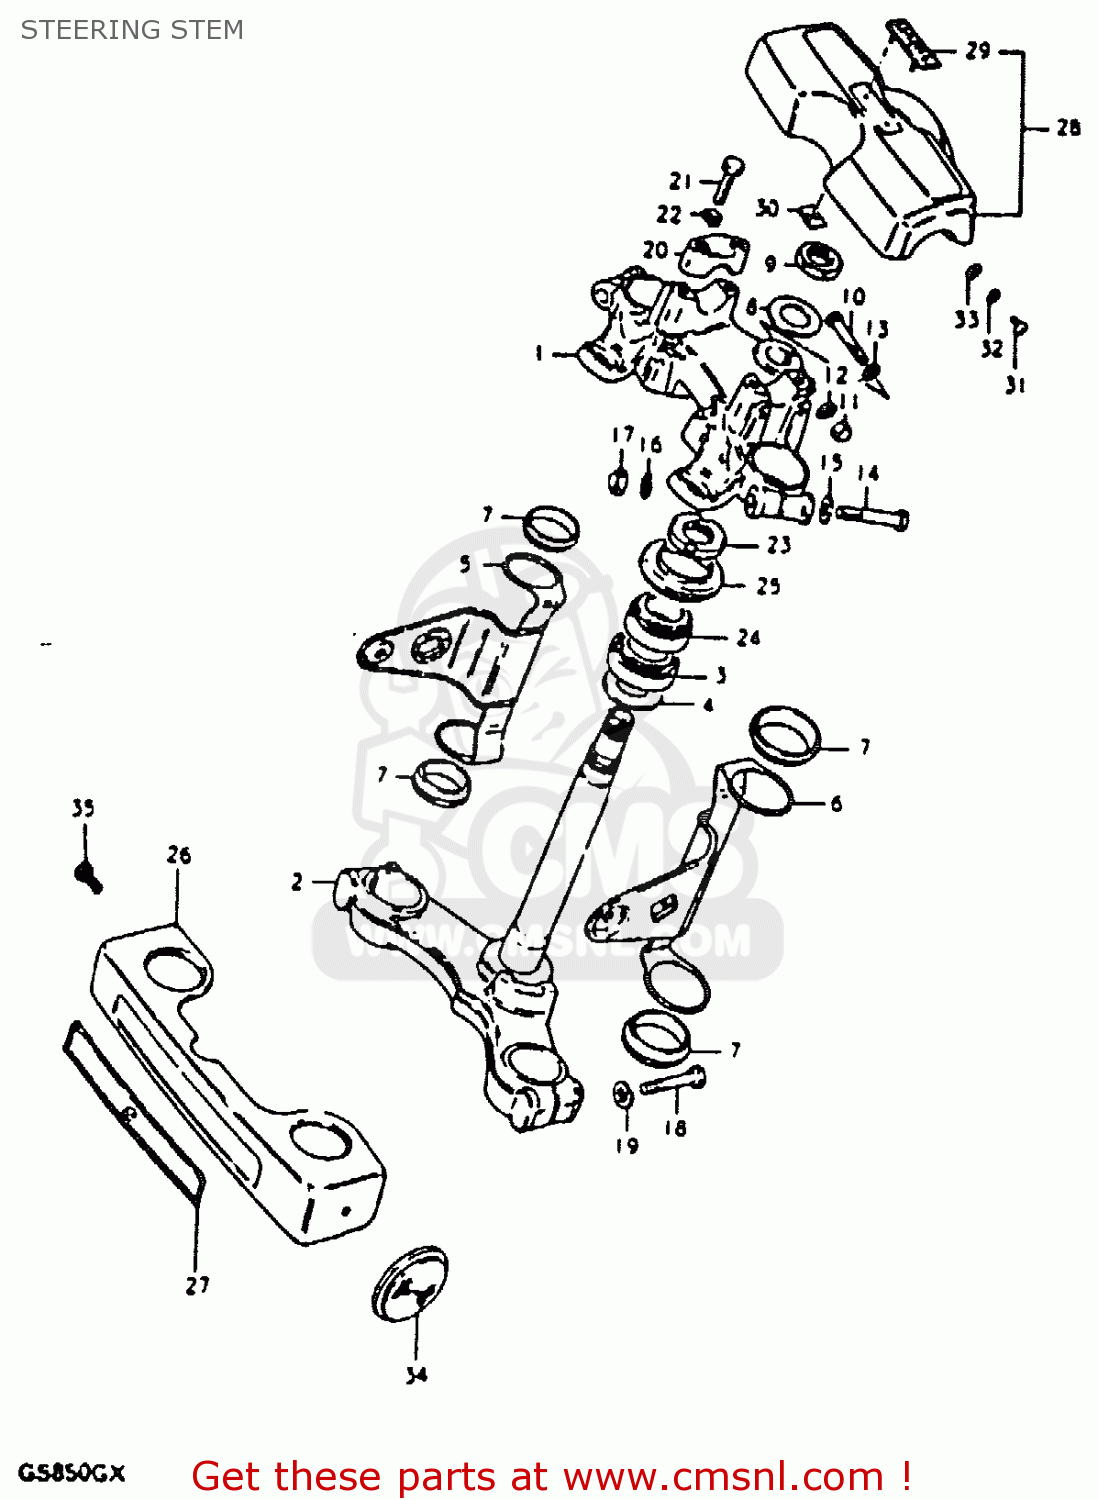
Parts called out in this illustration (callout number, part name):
1	HEAD,STEERING STEM
2	STEM,STEERING
3	BEARING
4	WASHER,THRUST
5	BRACKET,HEADLAMP,RIGHT
6	BRACKET,HEADLAMP,LEFT
7	CUSHION,HEADLAMP BRACKET
8	WASHER
9	NUT,FR FORK UPR BRACKET
10	BOLT 8X50
11	NUT
12	LOCK WASHER
13	WASHER
14	BOLT 10X55
15	WASHER
16	LOCK WASHER
17	NUT, LOWER LH
18	BOLT
19	LOCK WASHER
20	HOLDER,HANDLE(BLACK)
21	BOLT
22	LOCK WASHER
23	NUT,STEERING STEM(25X44X10)
24	TAPER,ROLLER BEARING
25	DUST SEAL,STEERING,UPPER
26	COVER,FRONT FORK
27	EMBLEM
28	PAD,HANDLEBAR
29	EMBLEM,HANDLE COVER PAD
30	NUT
31	SCREW
32	LOCK WASHER
33	WASHER
34	REFLEX REFLECTOR,RR
